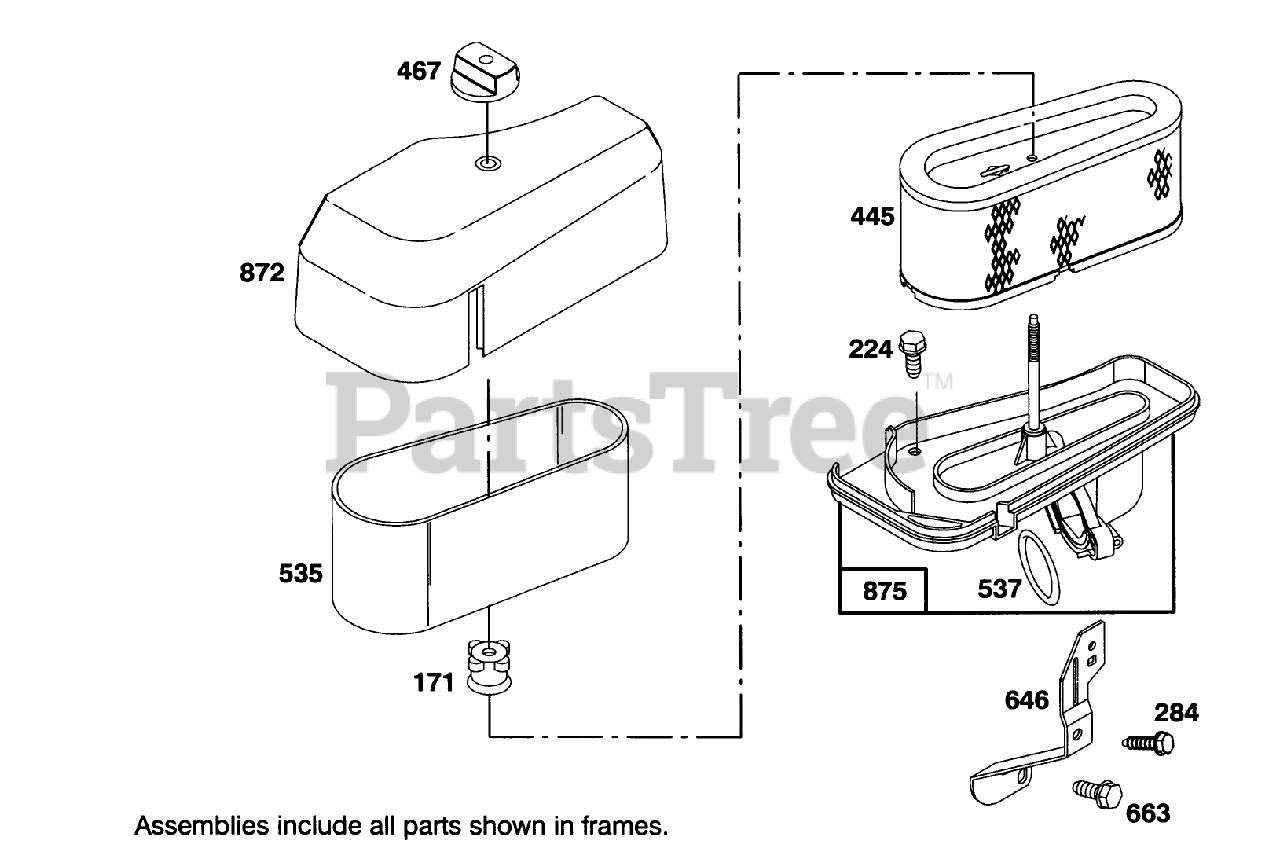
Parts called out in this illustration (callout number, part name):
224	Screw-Sem
284	Screw
445	Filter-Air
535	Filter-Air
537	O-Ring
646	Brace-Air Cleaner
663	Screw
872	Cover-Air Cleaner
875	Base-Air Cleaner
